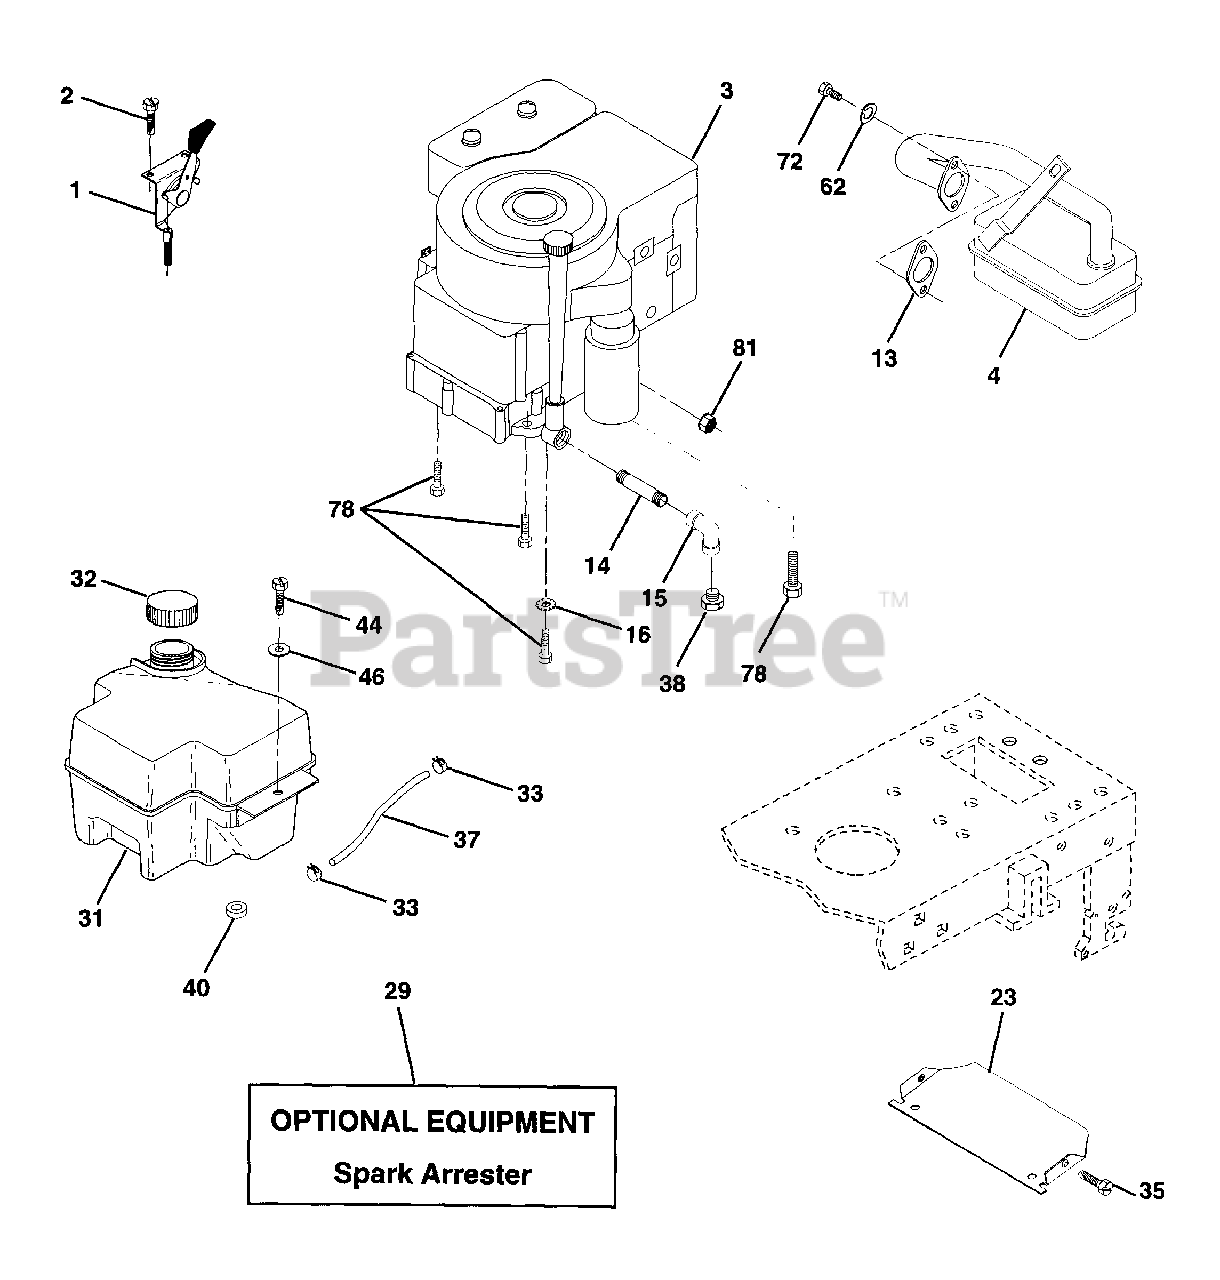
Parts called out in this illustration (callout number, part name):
1	Control Th/ch 23 5 LH Flag
2	Screw Hex Thd Cut 1/4-20 x 5/8 T
4	Muffler LT B&S 12/12.5/13HP
13	Gasket Eng 1 313 Id Tin Plated
14	Nipple Pipe 3/8 Npt X 3"
15	Elbow Std 90 Degree 3/8-18 Npt
16	Washer Lock Ext Tooth 3/8
23	Shield Heat
29	Kit Spark Arrestor (Flat Scrn)
31	Tank Fuel Front 2 00
32	Cap Asm Fuel W/sym Vented
33	Clamp Hose Black
35	Screw
37	Line Fuel 20"
38	Plug Oil Drain
40	Bushing Snap Nyl Blk Fuel Line
44	Screw Hexwsh Thdrol 1/4-20 x 3/4
46	Washer 9/32 X 7/8 X 16 Ga
62	Washer Lock Hvy Hlcl Spr 5/1 6
72	Screw Hexhd Cap 5/16-18 x 3/4
78	Screw Thdrol 3/8-16 x 1-1/4 TYTT
81	Nut Flange 1/4-20 Starter Nut
